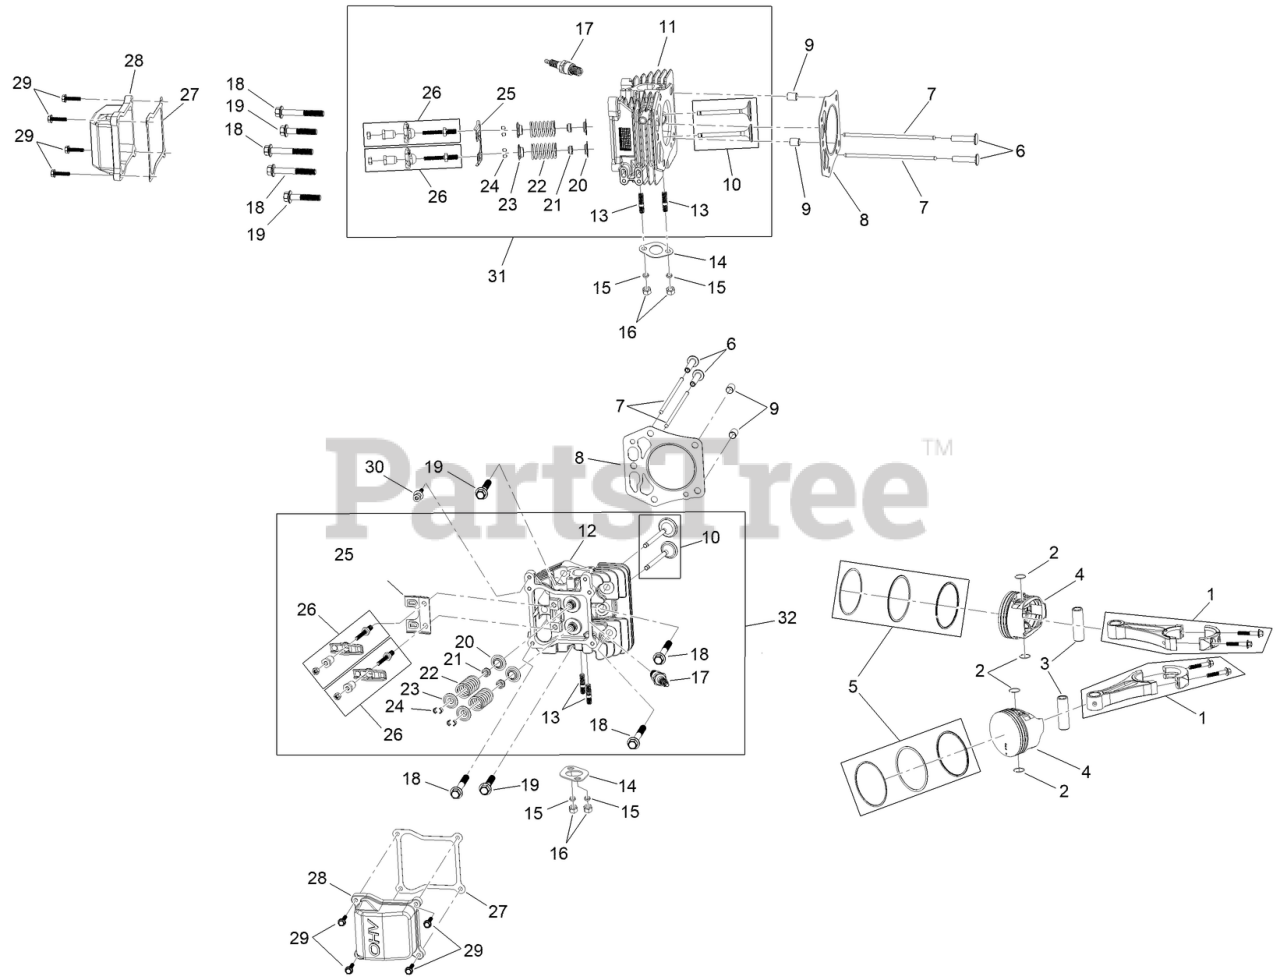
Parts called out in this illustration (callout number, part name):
1	CONNECTING ROD ASM
2	CLIP-PIN, PISTON
3	PIN-PISTON
4	PISTON
5	PISTON RING SET
6	LIFTER-VALVE
7	ROD-PUSH
8	GASKET-HEAD, CYLINDER
9	PIN-DOWEL
10	VALVE SET
11	HEAD-CYLINDER, RIGHT
12	HEAD-CYLINDER, LEFT
13	STUD-EXHAUST
14	GASKET-EXHAUST
15	WASHER-LOCK, SPLIT
16	NUT-HH
17	SPARK PLUG
18	SCREW-HWH
19	SCREW-HWH
20	SEAT-SPRING, VALVE
21	SEAL-STEM, VALVE
22	SPRING-VALVE
23	RETAINER-SPRING, VALVE
24	KEEPER-VALVE
25	PLATE-GUIDE, PUSH ROD
26	ROCKER ARM ASM
27	GASKET-VALVE COVER
28	COVER-VALVE
29	SCREW-HHF
30	SCREW-SHOULDER, HH
31	COMPLETE RIGHT HEAD ASM
32	COMPLETE LEFT HEAD ASM
